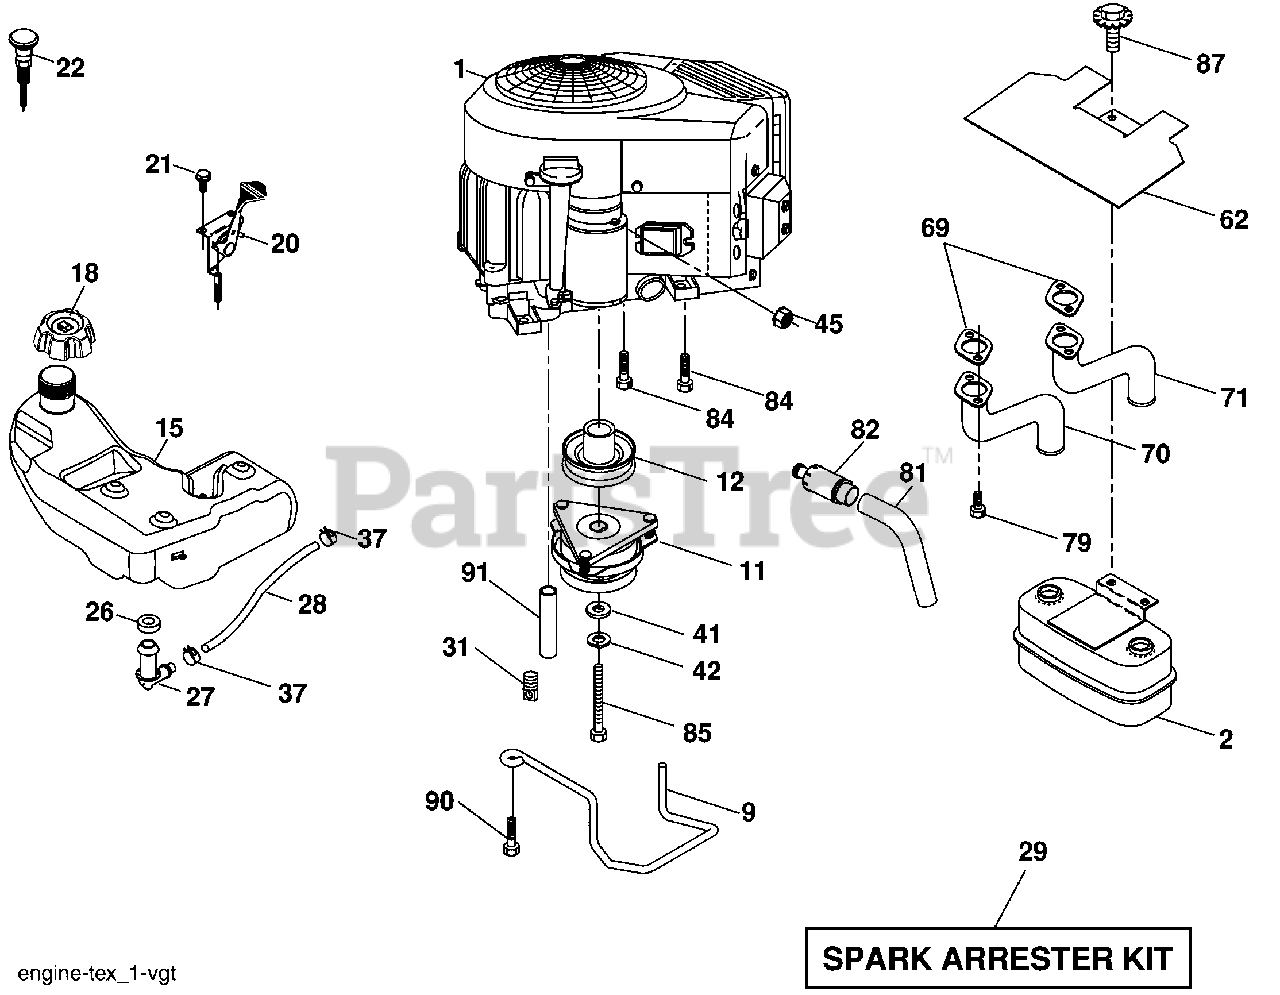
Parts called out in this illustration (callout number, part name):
9	Keeper Belt Engine
11	Clutch Electric
12	Pulley Engine
15	Tank Fuel 4.0
18	Cap Asm
20	Control Throttle
21	Screw 10 x 3/4 Single Lead Hex
22	Control Choke
28	Fuel Line
29	Spark Arrester Kit
31	Clip Push-In
37	Clamp Hose
41	Washer 1-1/2 OD x 15/32 ID x .250
42	Washer Lock 7/16
45	Nut Keps Hex 1/4-20 unc
62	Shield Heat Muffl er
70	Tube Exhaust LH
71	532 16 05-89 Tube Exhaust RH
79	532 18 39-06 Screw 5/16-18 x 1
81	532 14 84-56 Tube Drain Oil Easy
82	532 18 16-54 Plug Drain Oil
84	817 06 06-20 Screw 3/8-16 x 1 1/4
85	532 17 99-53 Bolt Hex 7/16-20 x 3.75 Gr. 5
87	532 19 82-39 Bolt 5/16-18 unc x 1 w/Sems
90	817 00 06-16 Screw 3/8-16 x 1
91	532 18 74-95 Bushing
